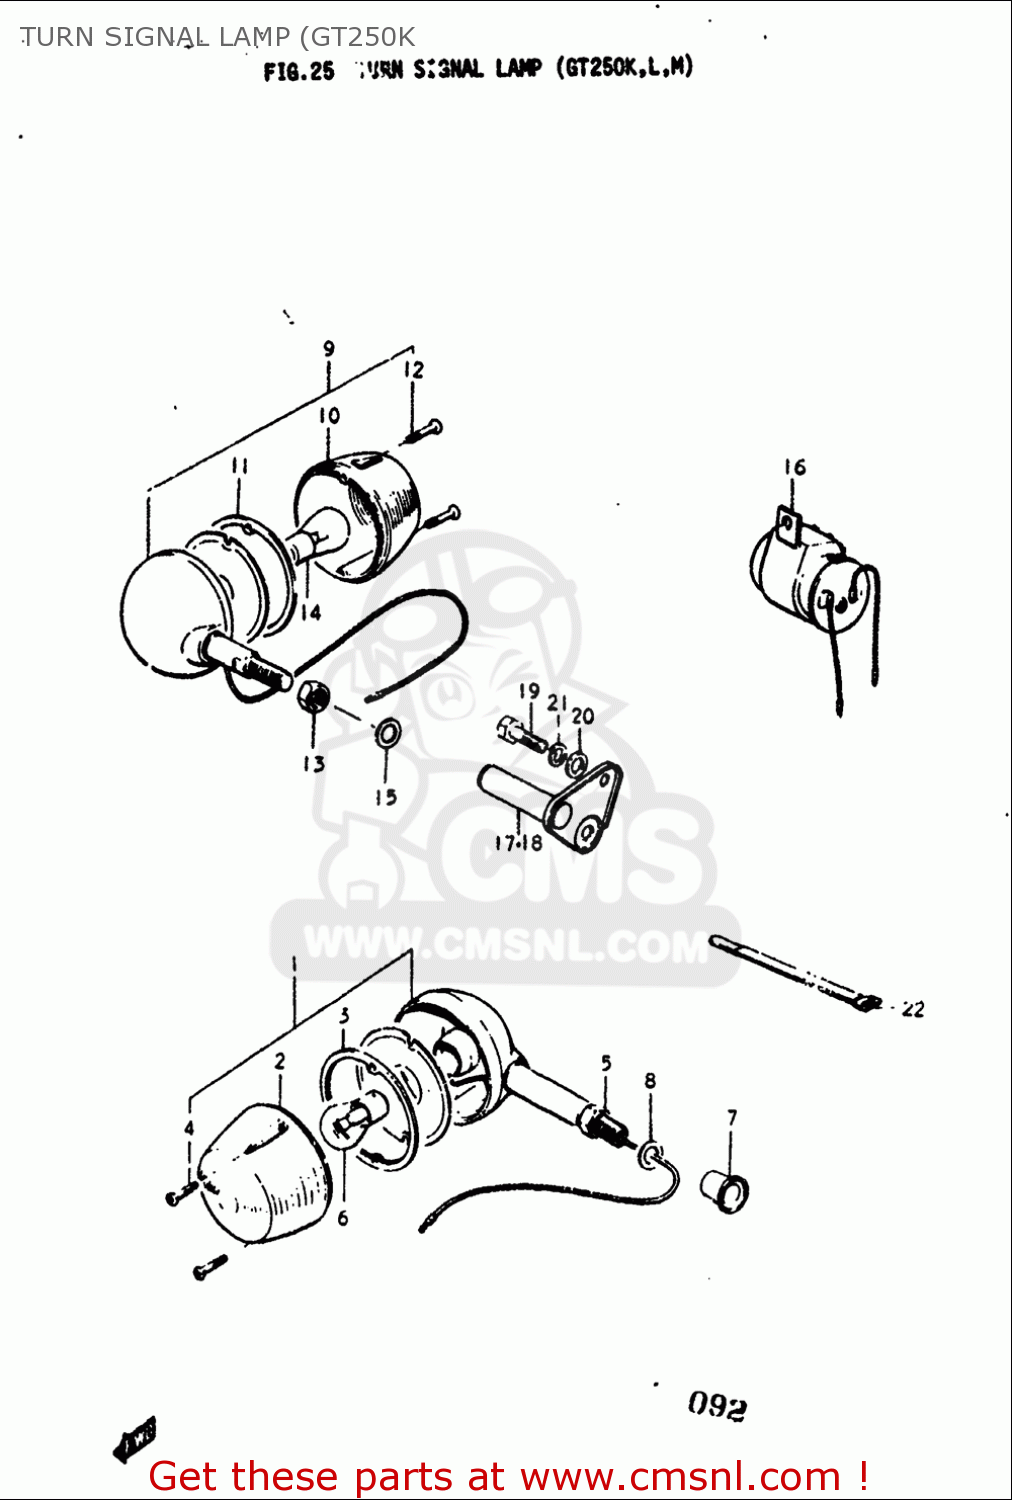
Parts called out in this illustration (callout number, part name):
1	LAMP ASSY,FR TURN SIGNAL
2	LENS,TURNSIGNAL
3	GASKET,TURNSIGNAL LENS (NAS)
4	SCREW
5	NUT
6	BULB(12V23W,STANLEY,A4577A)
7	COVER,FRONT TURN SIGNAL BRACKET
8	WASHER
9	LAMP ASSY,RR TURNSIGNAL
10	LENS,TURNSIGNAL
11	GASKET,TURNSIGNAL LENS (NAS)
12	SCREW
13	NUT
14	BULB(12V23W,STANLEY,A4577A)
15	WASHER
16	RELAY,TURN SIGNAL
17	BRACKET, REAR TURN SIGNAL RH
19	BOLT
20	WASHER
21	WASHER,LOCK
22	CLAMP
